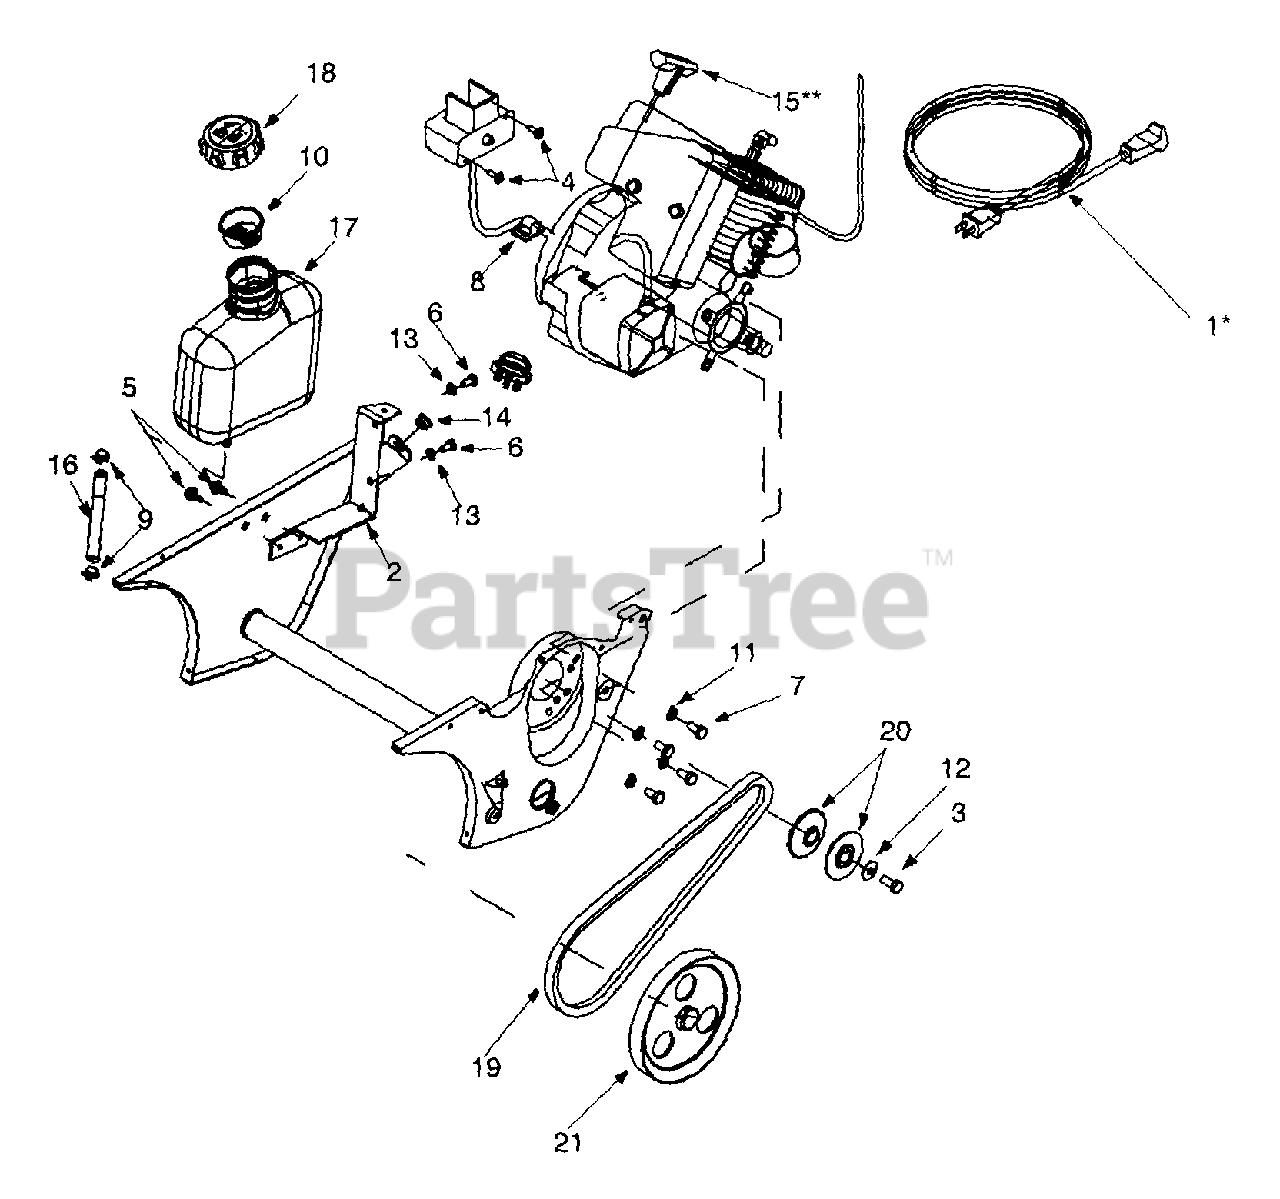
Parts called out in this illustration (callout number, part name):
1	Extension Cord "Electric start models only
4	Special Screw
5	Self-Tapping Screw
6	Hex Screw 114-20 x .50"
7	Hex Screw 5/16-24 x 625
8	Mounting Clamp
9	Hose Clamp
11	Lock Washer
12	Beleville Washer
13	Lock Washer
14	Plastic Bushing
15	Recoil Handle
16	Fuel Line Hose
17	Fuel Tank: 2 Quart
18	Fuel Cap
19	V-Belt
20	V-Pulley Half
21	Pulley
